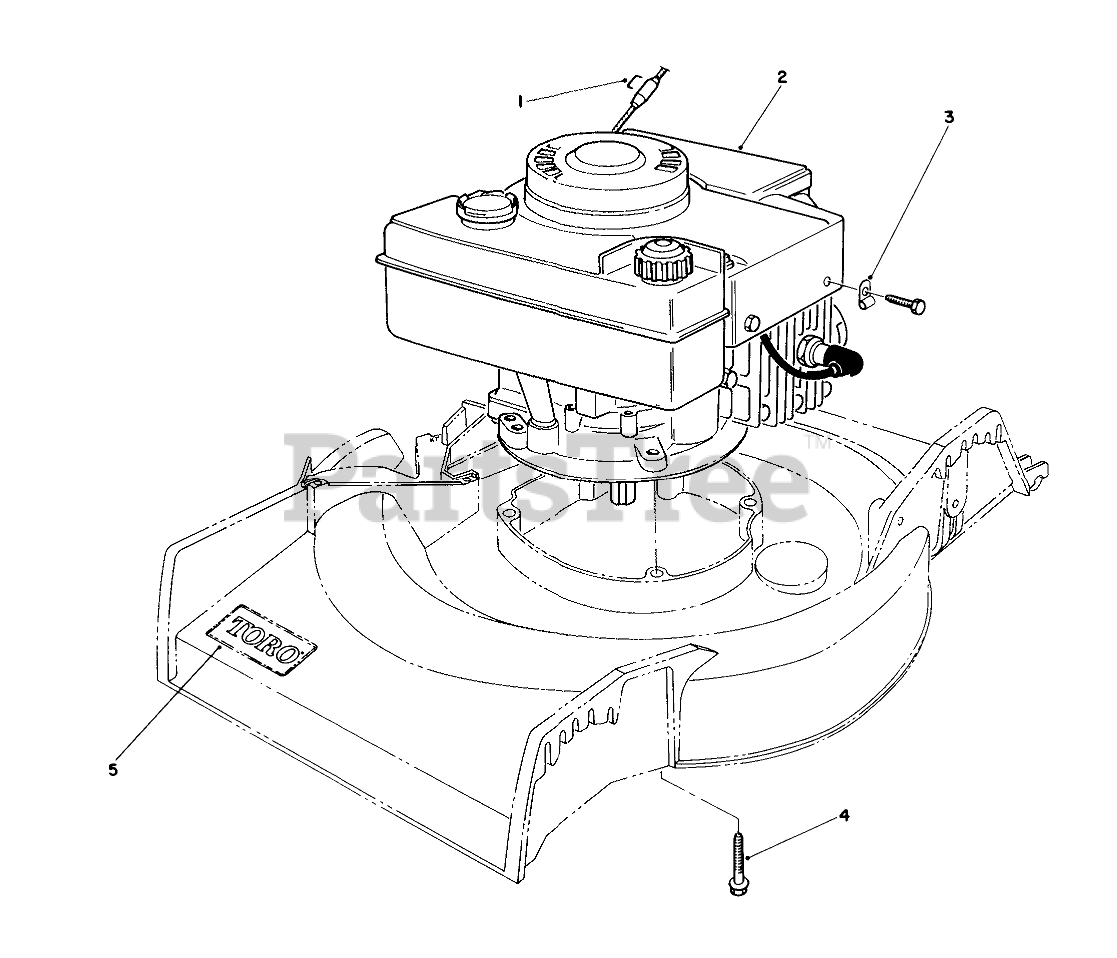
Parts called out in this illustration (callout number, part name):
1	Staple
3	CLAMP
4	SCREW-HWHTF
5	DECAL
